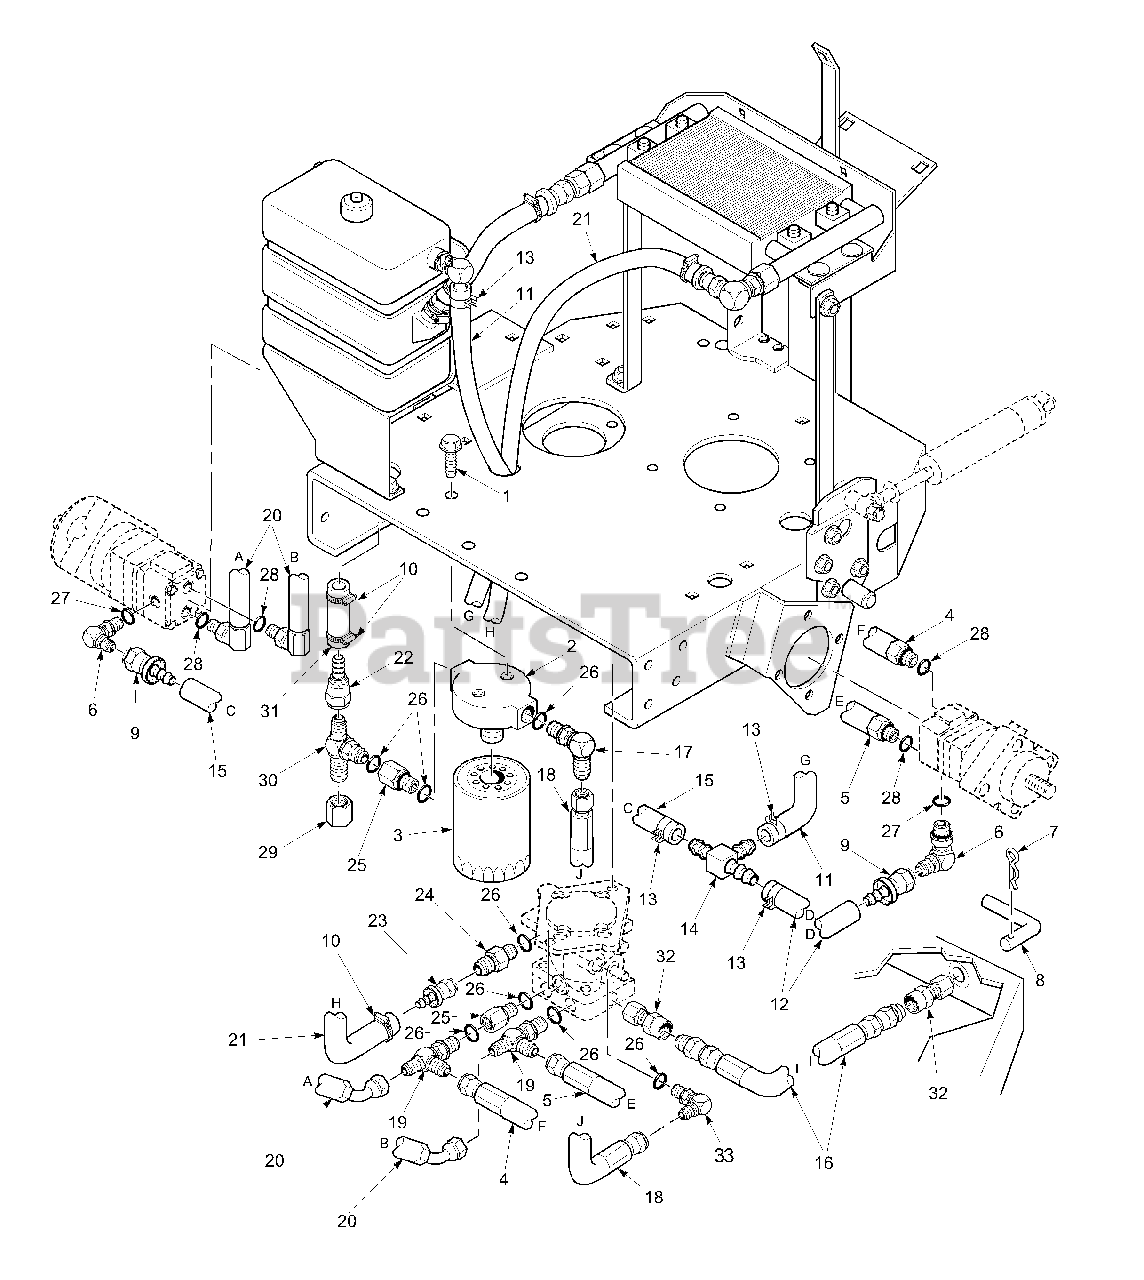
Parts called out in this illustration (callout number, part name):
1	Capscrew, 1/4-20 x 1/2 Serr. Fl. Hex Head
2	Filter Head
3	Filter, Spin-On Lube
4	Hose Assembly
5	Hose Assembly
6	Elbow, 90 Degrees
7	Hairpin Cotter
8	Lever, Dump Valve
9	Connector, Flare Swivel with Hose Barb
10	Hose Clamp
11	Hose, 1/4 Pushlock, Order by the inch
12	Hose, 1/4 Pushlock, Order by the inch
13	Hose Clamp
14	Tee Union, Pushlock Hose
15	Hose, 1/4 Pushlock, Order by the inch
16	Hose, Dump Valve
17	Elbow, 90 Deg.
18	Inlet Hose, 3/4" ID
19	Tee, 1/2" Run
20	Motor Hose
21	Hose, Pump To Oil Cooler
22	Coupling, Flare Swivel
23	Coupling, Flare Swivel With Barb
24	Tube Union
25	O-Ring Bushing
26	O-Ring
27	O-Ring
28	O-Ring
30	Tee, JIC to O-Ring
31	Hose, Order by the inch
32	Compression Fitting
33	Elbow, 90 Deg.
